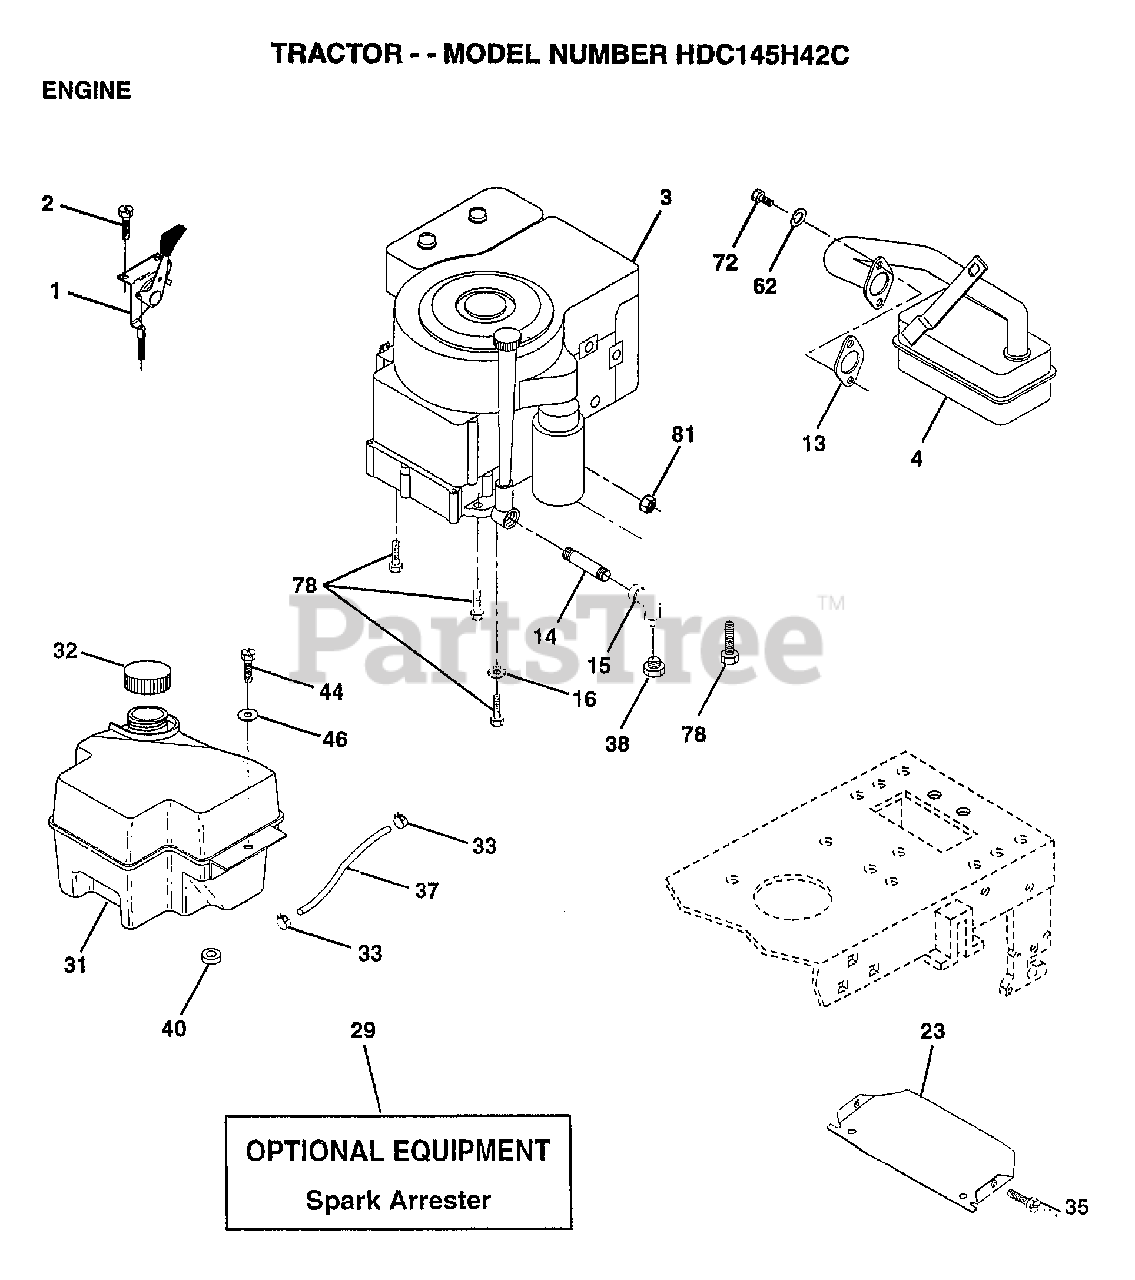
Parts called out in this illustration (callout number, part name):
1	CONTROL THROTTLE
2	SCREW LT
4	MUFFLER
13	GASKET ENG 1 313 LD TIN PLATED
14	PIPE NIPPLE
15	ELBOW
16	LOCKWASHER
23	SHIELD-HEAT
32	CAP ASM FUEL
33	HOSE CLAMP
35	SCREW
37	LINE FUEL
44	SCREW HEX CRT
46	WASHER
62	LOCKWASHER
72	SCREW
78	SCREW
81	NUT
